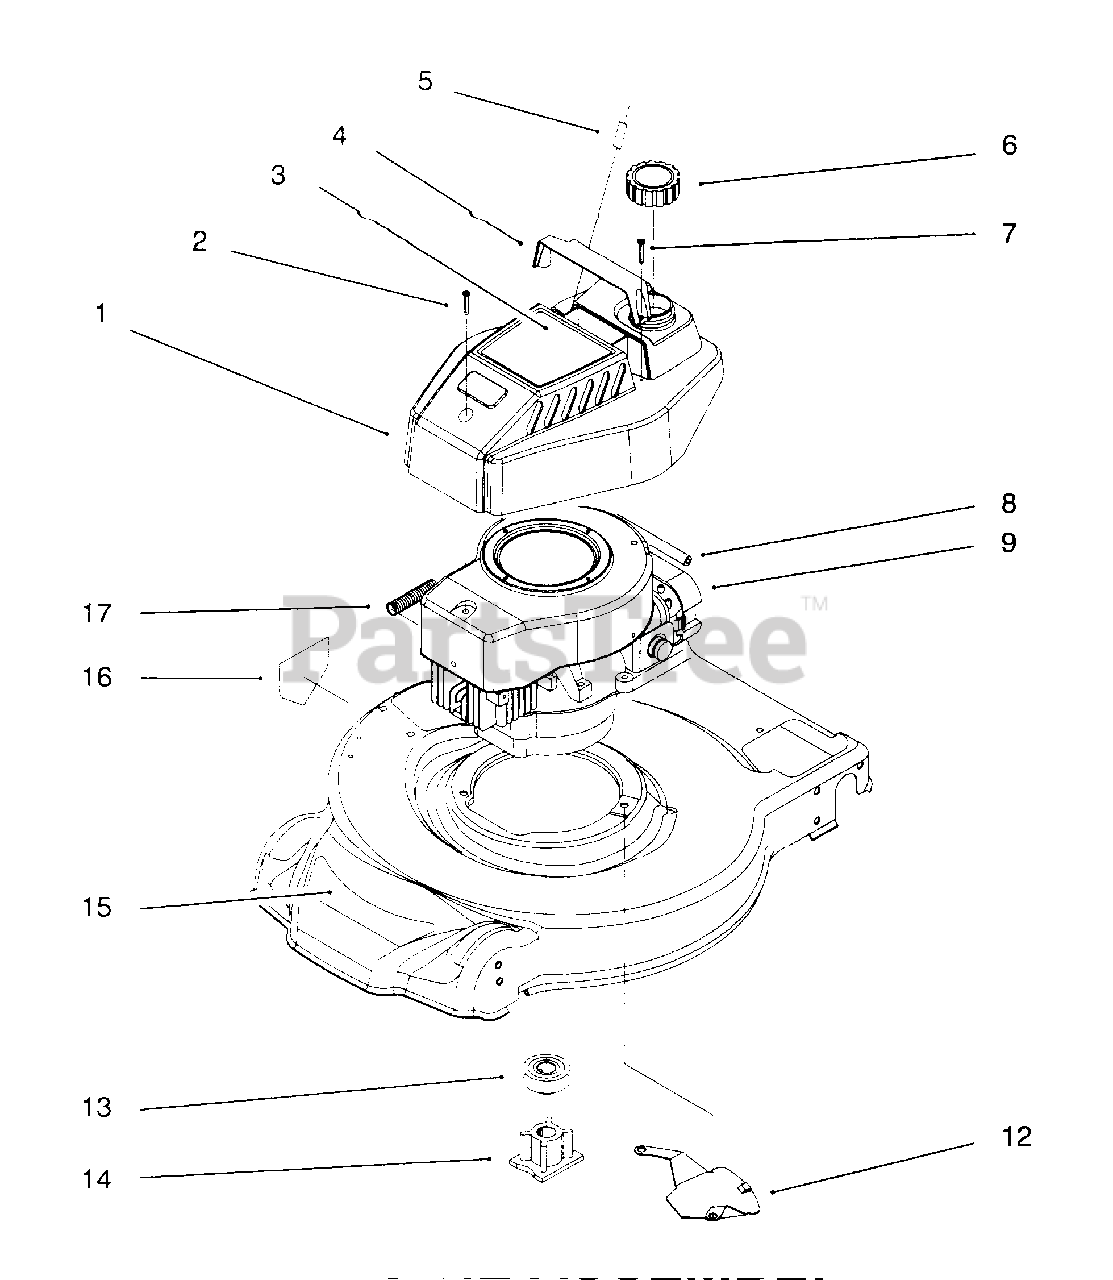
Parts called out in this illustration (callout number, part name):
2	Decal-Recoil
3	Applique-Shroud
4	Screw-Tapping
5	Screw-Tapping
6	Guide-Belt
